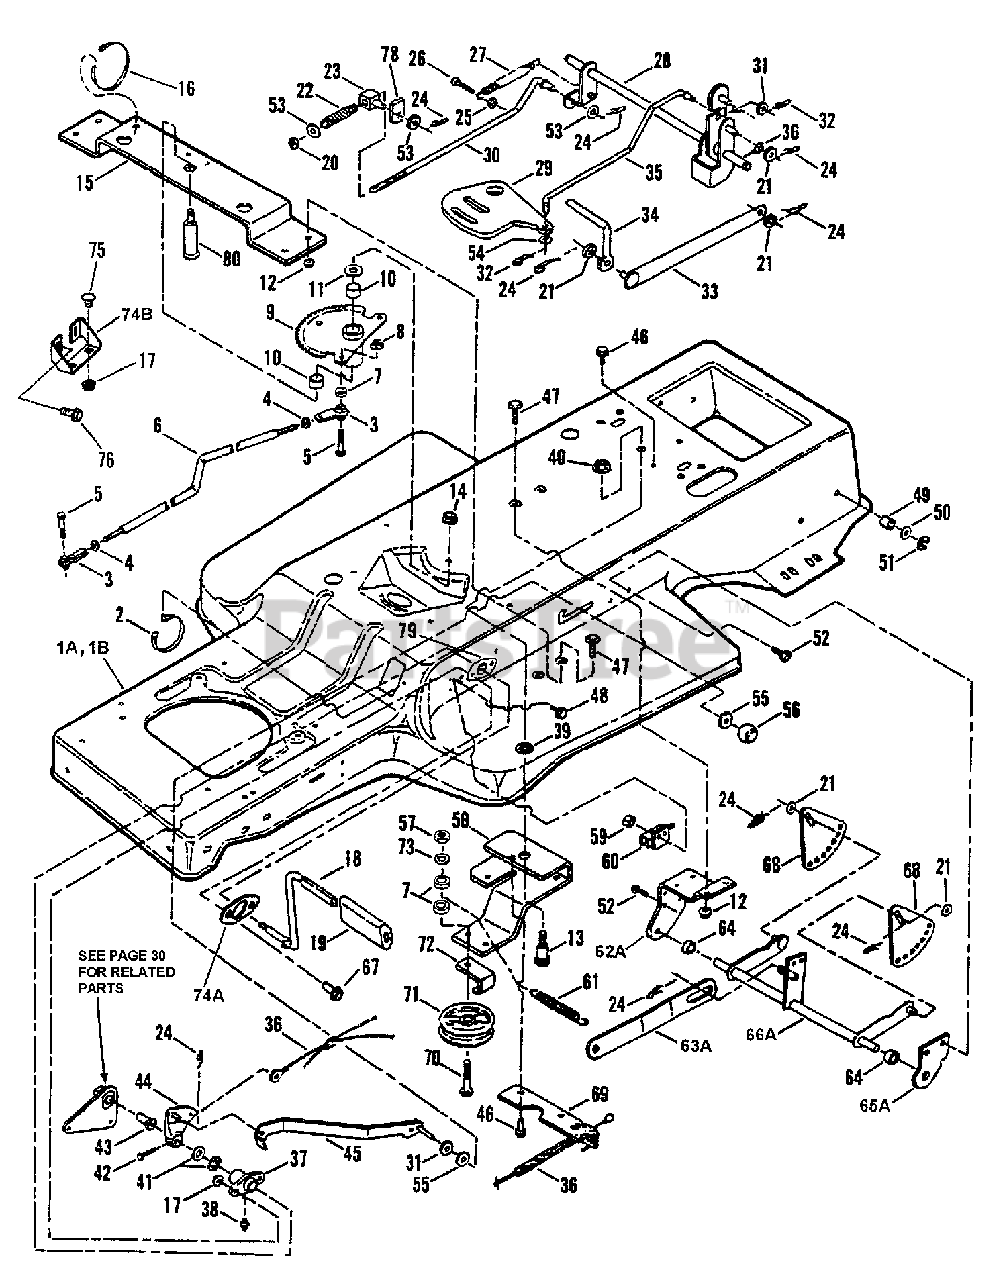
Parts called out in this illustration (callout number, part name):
1A	FRAME, Tractor
1B	FRAME, Tractor
2	TIE, Wire
3	BALL JOINT, 3/8-24
4	NUT, 3/8-24 Hex Jam
5	SCREW, 3/8-24 x 1-1/4" Hex Head Cap, Grade 2
6	LINK, Drag
7	SPACER
8	NUT, 3/8-16 Hex Flange Lock
9	ASS'Y, Sector Gear
10	BEARING, Sector Gear
11	WASHER, 3/4 Thrust
12	NUT, 1/4-20 Hex Flange Lock
13	BOLT, 1/2-13 x 2" Shoulder
14	NUT, 1/2-13 Hex Ctr. Lock, Gr. A
15	BRACE, Sector Gear
16	TIE, Cable 7"
17	NUT, 5/16-18 Hx. Flg. Lk., Gr 5
18	PEDAL, Clutch Brake
19	PAD, Pedal
20	NUT, 3/8-16 Hex Nyloc
21	WASHER, 3/8 Bright Zinc, Flat
22	SPRING, Brake
23	SWIVEL, Inline Brake
24	PIN, 3/8 x 1-7/32" Cotter (Self- Locking)
25	NUT, 5/16-18 Hex Center Lock
26	SCREW, 5/16-18 x 1-1/4" Self-Tap
27	SPRING
28	WELDMENT, Brake Arm
29	ARM, Transmission Speed Control
30	ROD, Brake
31	WASHER, 5/16 Flat
32	PIN, 5/16 Cotter, Self-Locking
33	LINK, Shift
34	ASSEMBLY, Shift Lever (Lower)
35	LINK, Speed (Lower)
36	ASSEMBLY, Clutch/Brake Cable
37	ASSEMBLY, Foot Shaft Pivot
38	LUBE FITTING, Straight (press-fit for .187 dia. Hole)
39	WASHER, 1/2 Internal Tooth Lock
40	NUT,1/2-13 Hex Flange Lock
41	WASHER, 5/8 Flat
42	PIN, 3/16 x 1-1/2" Clevis
43	BEARING, Flange
44	ASSEMBLY, Clutch Brake Arm
45	LATCH, Park Brake
46	SCREW, 5/16-18 x 5/8" S. Tap
47	BOLT, 1/4-20 x 5/8" Carriage
48	SCREW, #10-32 x 5/8" H.W.H.
49	BUSHING, Nylon 1/2
50	WASHER, 1/2 Flat
51	RING, 1/2" External Retaining
52	SCREW, 5/16-18 x 5/8" Truss Head (Torx)
53	WASHER, 3/8" Flat
54	WASHER, 1/16" x 11/32" I.D. x 5/8" O.D.
55	WASHER, 5/16 Nylon
56	KNOB, Push/Pull (5/16-18 Thd.)
57	NUT, 3/8-16 Hex, Grade B or 5
58	ARM, Idler (Traction Drive)
59	NUT, #10-32 Hex Nyloc
60	SWITCH (NO/NC)
61	SPRING, Traction Drive
62A	BRACKET, Rear Lift/PTO Lever
63A	LINK, Lift
65A	BRACKET, Deck Hang Pivot
66A	WELDMENT, Rear Lift
67	SCREW, 5/16-18 x 7/8" Truss Head (Torx)
68	PLATE, Lift Sector
69	EXTENSION, Idler Arm
70	SCREW, 3/8-16 x 2-1/4" Hex Head Cap, Grade 5
71	PULLEY, Flat Idler, 3.47 O.D.
72	GUIDE, Pulley
73	WASHER, 3/8" Split Lock
74A	WASHER, Pivot, Stiffener
74B	BRACKET, Frame Brace
75	BOLT, 5/16-18 x 5/8" Short Neck Carriage, Grade 5
76	SCREW, 5/16-18 x 3/4" HWST
78	BRAKE ARM, Transmission
79	KIT, Frame Stiffening
80	BOLT, Shoulder 3 7/8" x 1/2" - 13
